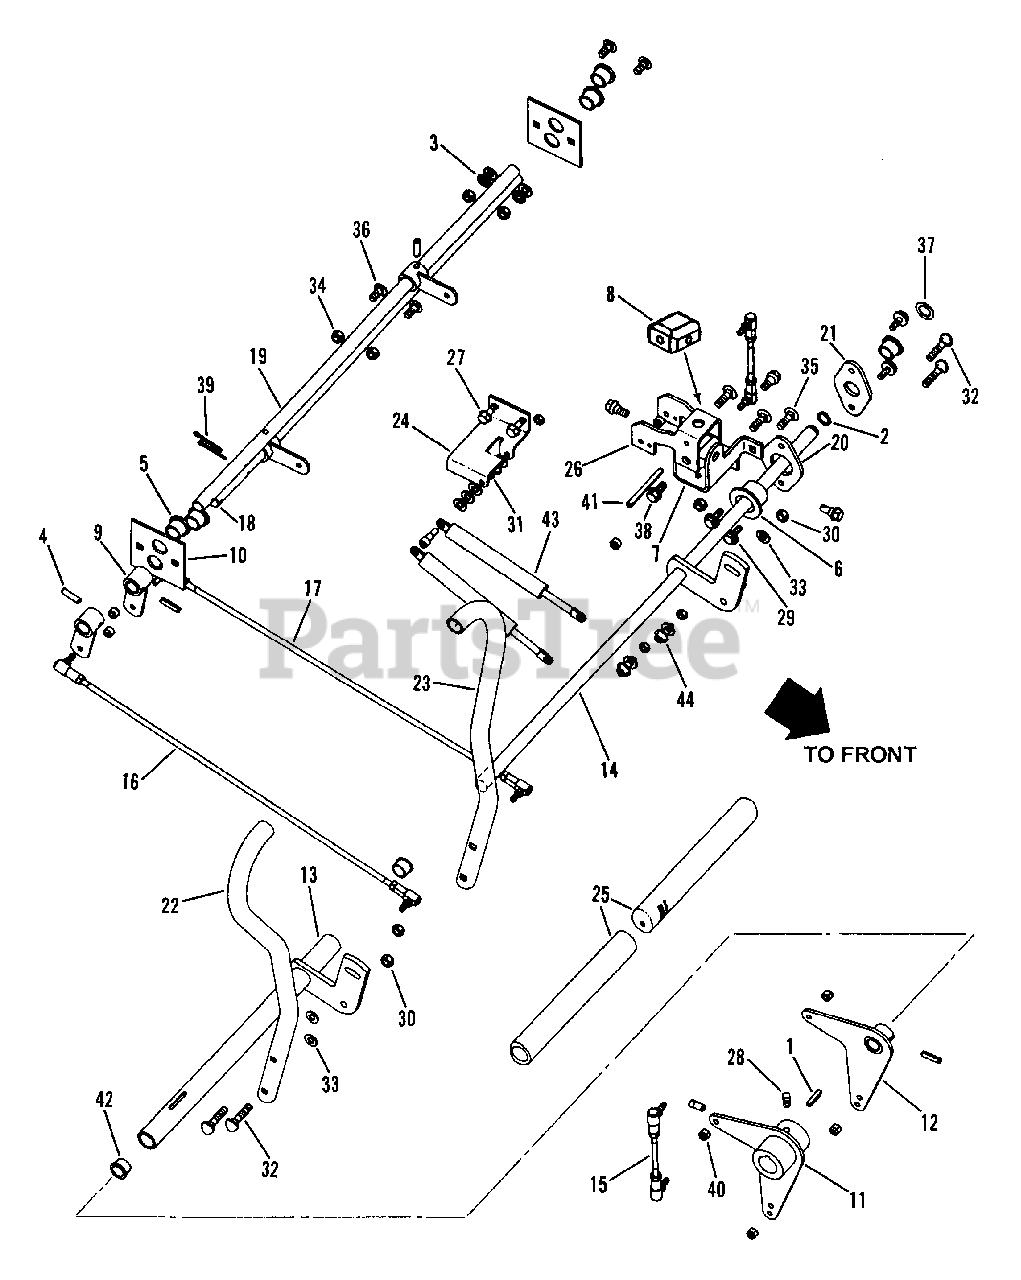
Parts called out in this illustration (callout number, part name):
1	KEY, 3/16" Square x 1"
2	RING, 5/8" External Retaining
3	RETAINER, 5/16" Bolt
4	ROLL PIN, 1/4" x 1"
5	BUSHING, 5/8 I.D. x 5/8"
6	BUSHING, Caster
7	BRACKET, Joystick Mounting
8	BLOCK, Pivot
9	WELDMENT, Arm/Hub
10	PLATE, Bushing, Hydro Shaft
11	WELDMENT, R. H. Control Bellcrank
12	WELDMENT, L. H. Control Bellcrank
13	WELDMENT, R. H. Control
14	WELDMENT, L. H. Control
15	ASSEMBLY, Ball Joint Link 5.12"
16	ASSEMBLY, Ball Joint Link 20.4"
17	ASSEMBLY, Ball Joint Link 20.56"
18	HYDRO SHAFT, L.H.
19	HYDRO SHAFT, R.H.
20	PLATE, R.H. Bearing
21	PLATE, L.H. Bearing (Twin-Stick Z Mower)
22	ARM, R.H. Twin Stick Control
23	ARM, L.H. Twin Stick Control
24	BRACKET, Dampener Mounting
25	GRIP, Twin Stick
26	BRACKET, Joystick Control
27	SCREW, 5/16-18 x 5/8" Hex Washer Self-Tap
28	SET SCREW, 5/16-18 x 1/2" Square Head Cup Point
29	SCREW, 1/4-20 x 5/8" Hex Head Self-Tap
30	NUT, 5/16-18 Hex Center Lock, Grade 8
31	NUT, 1/4-20 Hex Center Lock, Grade 5 or B
32	BOLT, 5/16-18 x 1-1/2" Curved Head Square Neck
33	WASHER, .34 I.D. Flat
34	NUT, 5/16-18 HEX NYLON LOCK
35	BOLT, 5/16-18 x 1" Round Head Short Neck Carriage, Grade 5
36	BOLT, 5/16-18 x 3/4" Round Hd. Short Neck Carriage, Grade 5
37	WASHER, 5/8" I.D. Flat
38	BOLT, 5/16-18 Shoulder
39	COTTER PIN, 1/8 x 1-1/4"
40	NUT, 1/4-28 Hex Nyloc
41	ROLL PIN, 1/4 x 2-3/4"
42	BUSHING, .632 I.D. x .753 O.D. Teflon Impregnated
43	CYLINDER, Dampener
44	BOLT, 1/4-20 Socket Head Shoulder
